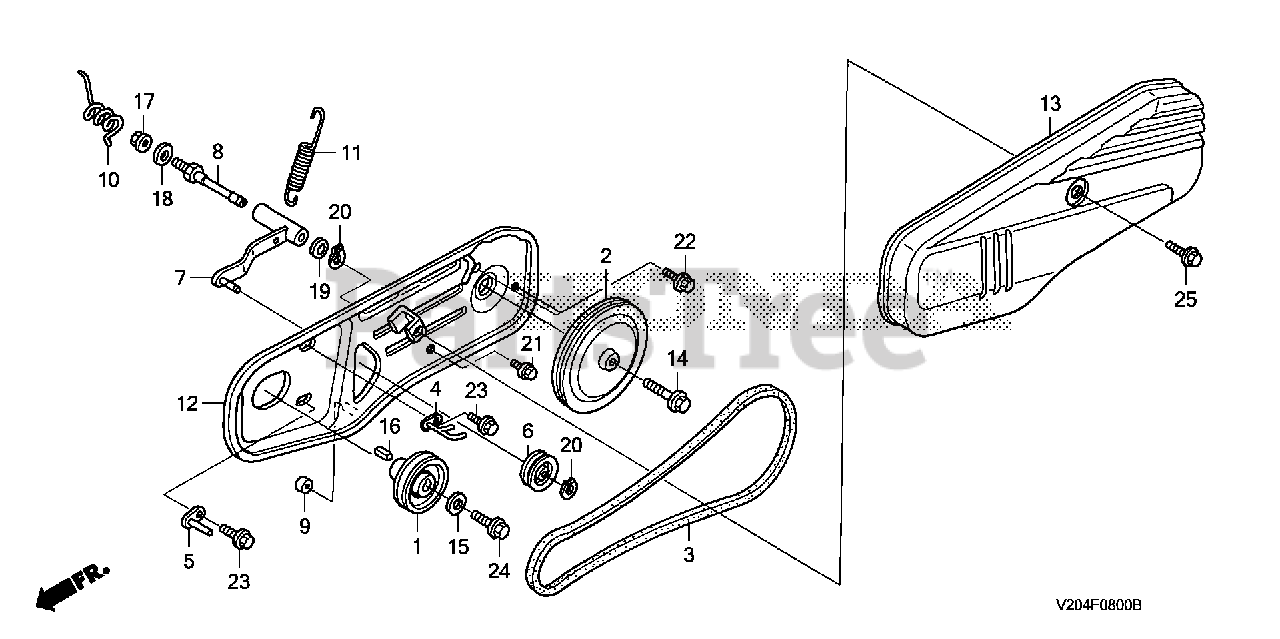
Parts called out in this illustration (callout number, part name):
1	PULLEY, DRIVE (80MM)
2	PULLEY, DRIVEN (165MM)
3	V-BELT (SB-48)
4	STOPPER, BELT
5	STOPPER A, BELT
6	ROLLER, TENSIONER
7	ARM, TENSION *NH105* (MAT BLACK)
8	SHAFT, TENSIONER ARM
9	STOPPER, TENSIONER ARM
10	SPRING, TENSIONER ARM RETURN
11	SPRING, BELT TENSIONER
12	COVER, BELT (INNER) *R280* (POWER RED)
13	COVER, BELT *R280* (POWER RED)
14	BOLT, FLANGE (8X18)
15	WASHER, LOCK (8MM)
16	KEY (7X7X33)
16	KEY (7X7X30)
17	NUT, FLANGE (10MM)
18	WASHER, PLAIN (10MM)
19	WASHER, PLAIN (12MM)
20	CIRCLIP (OUTER) (12MM) Use up to Engine SN 2056819.
21	BOLT, FLANGE (6X10)
22	BOLT, FLANGE (8X12)
23	BOLT, FLANGE (8X16)
24	BOLT, FLANGE (8X28)
25	BOLT, FLANGE (10X16)
